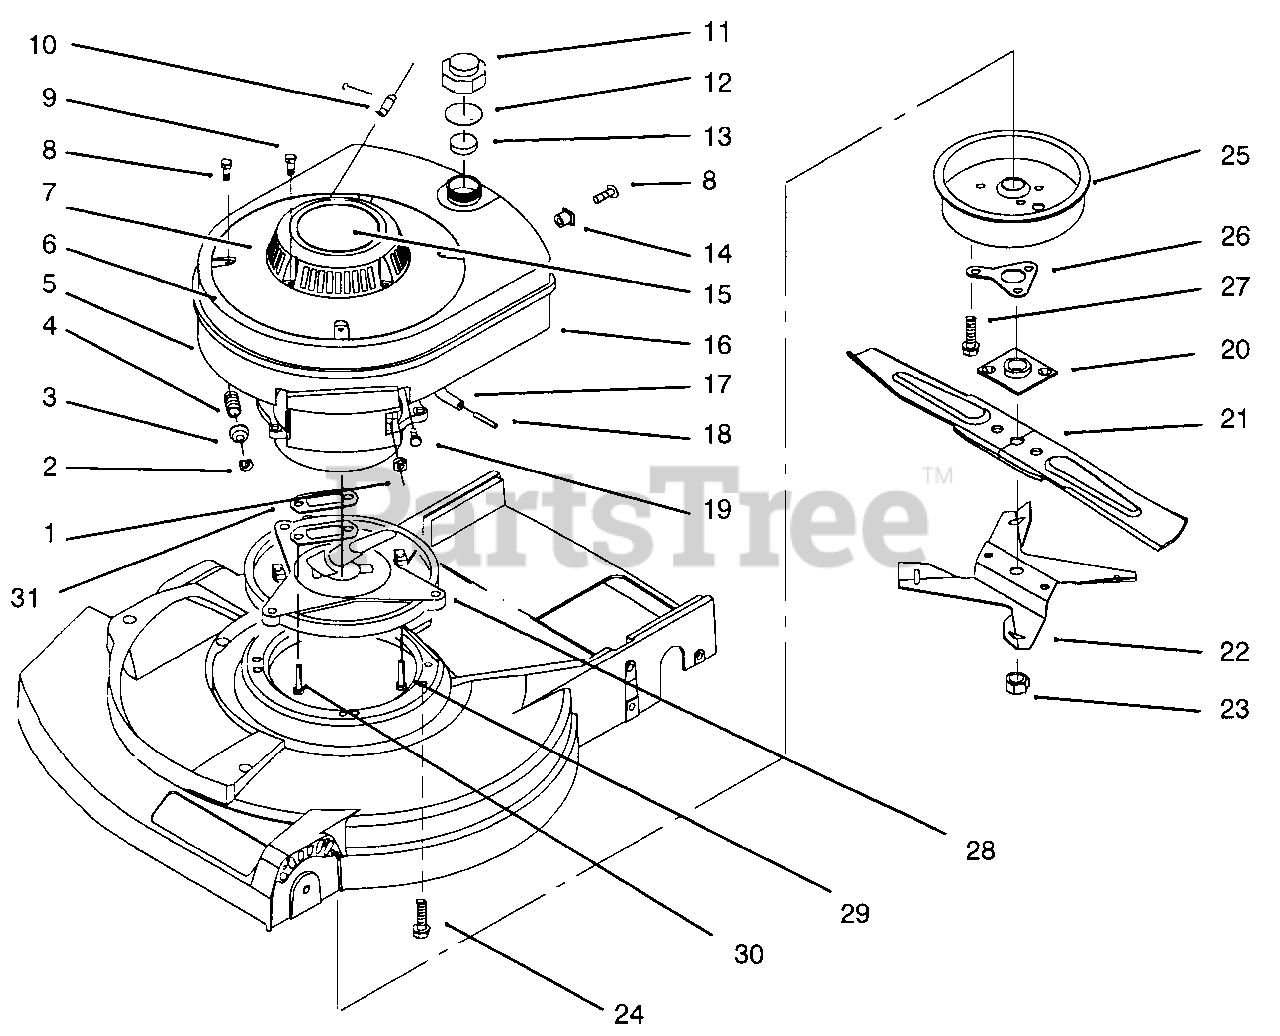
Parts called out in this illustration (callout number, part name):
1	Nut
2	Retainer
3	Actuator-Lever Brake
5	Shroud & Tank Assembly
6	Base-Starter
7	Starter Assembly
8	Screw-Self Tapping
10	Stop-Rope
11	Cap-Fuel
12	Gasket-Fuel Cap
13	Baffle Fuel Cap
14	Grommet
15	Decal-Recoil (Hand Push)
16	Engine Assembly
17	Line-Fuel
18	Screen-Fuel Line
20	Plate & Collar Assembly
21	Blade 21"
22	Fan-Mulching
23	Nut-Blade
24	Screw-Engine
25	Muffler Cover Assembly
26	Support-Crankshaft
28	Plate-Muffler
31	Gasket-Muffler
